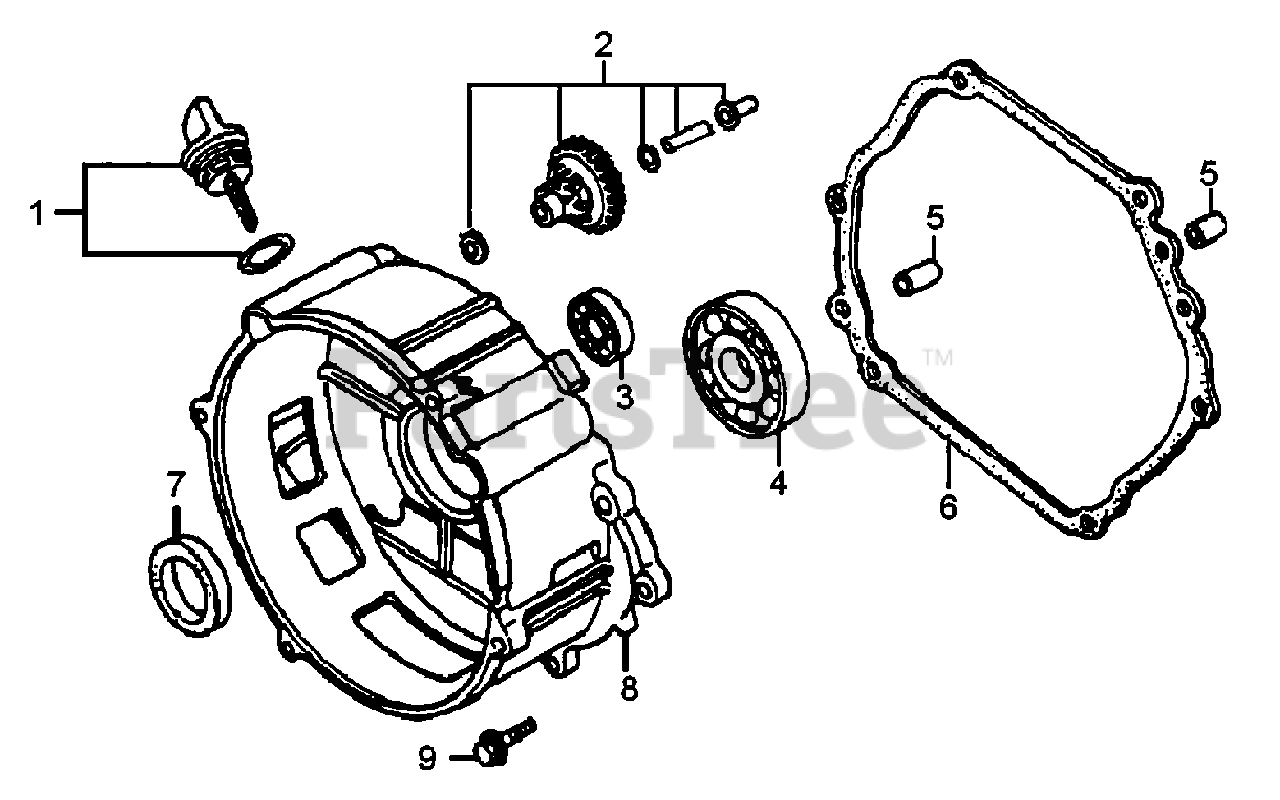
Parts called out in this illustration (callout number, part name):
1	CAP, OIL FILLER
2	GOVERNOR ASSY.
3	BEARING, RADIAL BALL 6202
4	BEARING, RADIAL BALL 6207
5	PIN, DOWEL 8X12
6	GASKET, CASE COVER
7	SEAL, OIL 35X52X7
8	COVER, CRANKCASE
9	BOLT, FLANGE M8X40
